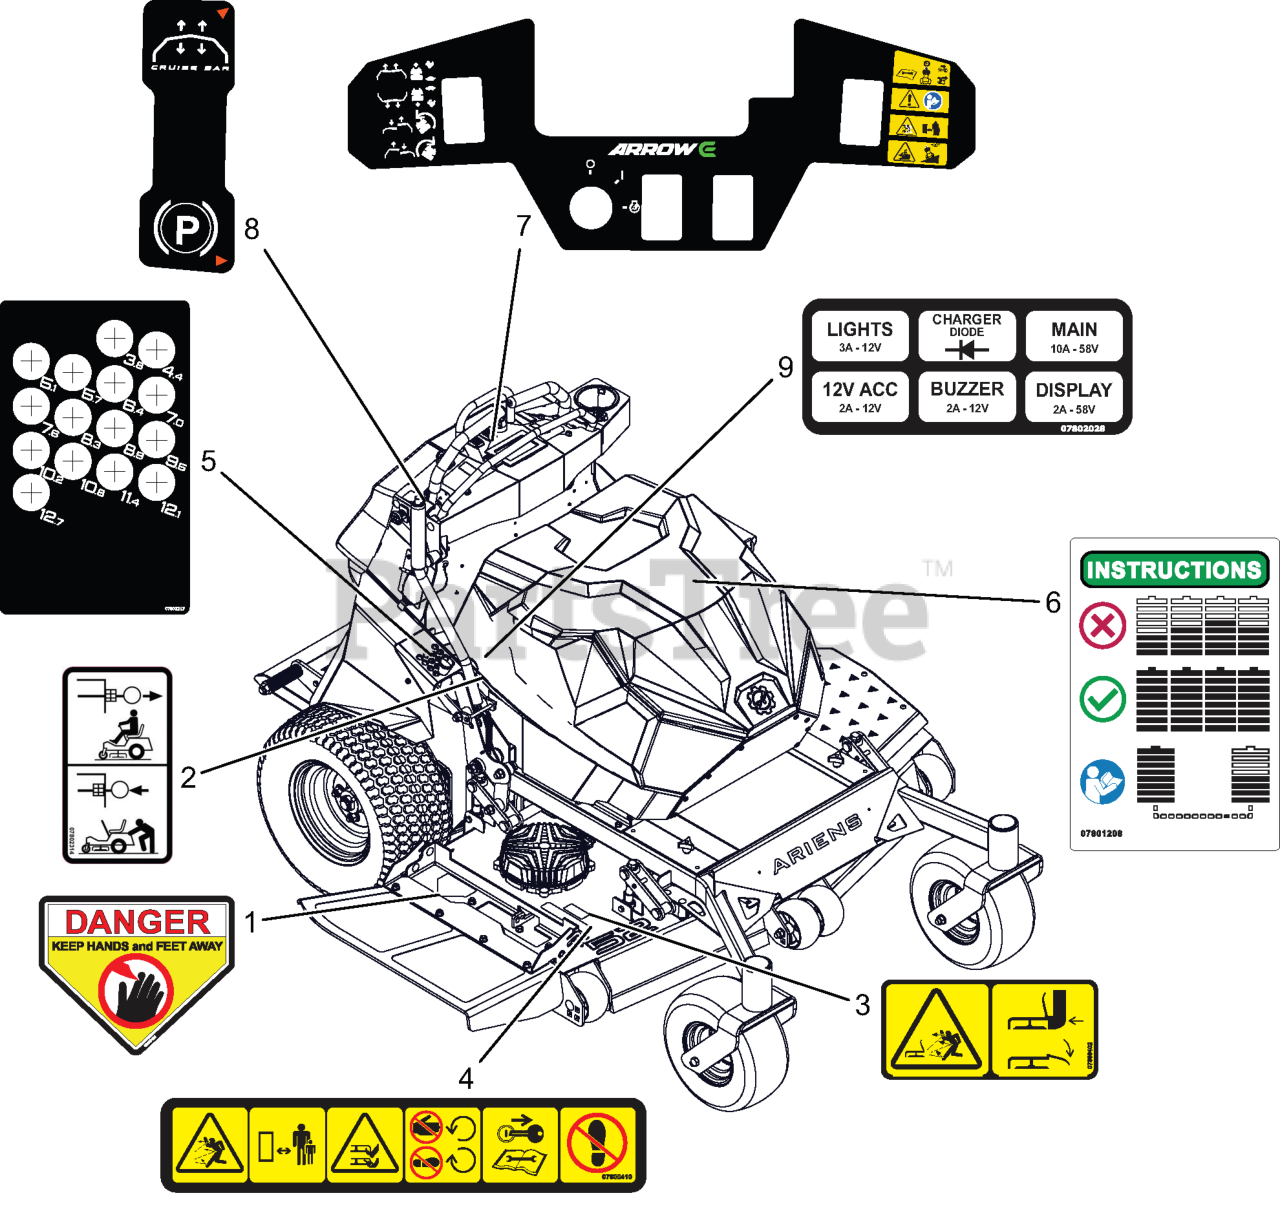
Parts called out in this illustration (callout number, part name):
1	DECAL, DANGER
2	DECAL, TRANSMISSION DISCONNECT
3	DECAL, SAFETY - DECK GUARDING
4	DECAL, DECK SAFETY
5	DECAL, ARROW E HEIGHT ADJUST
6	DECAL, BATTERY BALANCE
7	DECAL, ARROW E DASH
8	DECAL, ARROW E DASH CRUISE BAR
9	DECAL, FUSE LAYOUT
